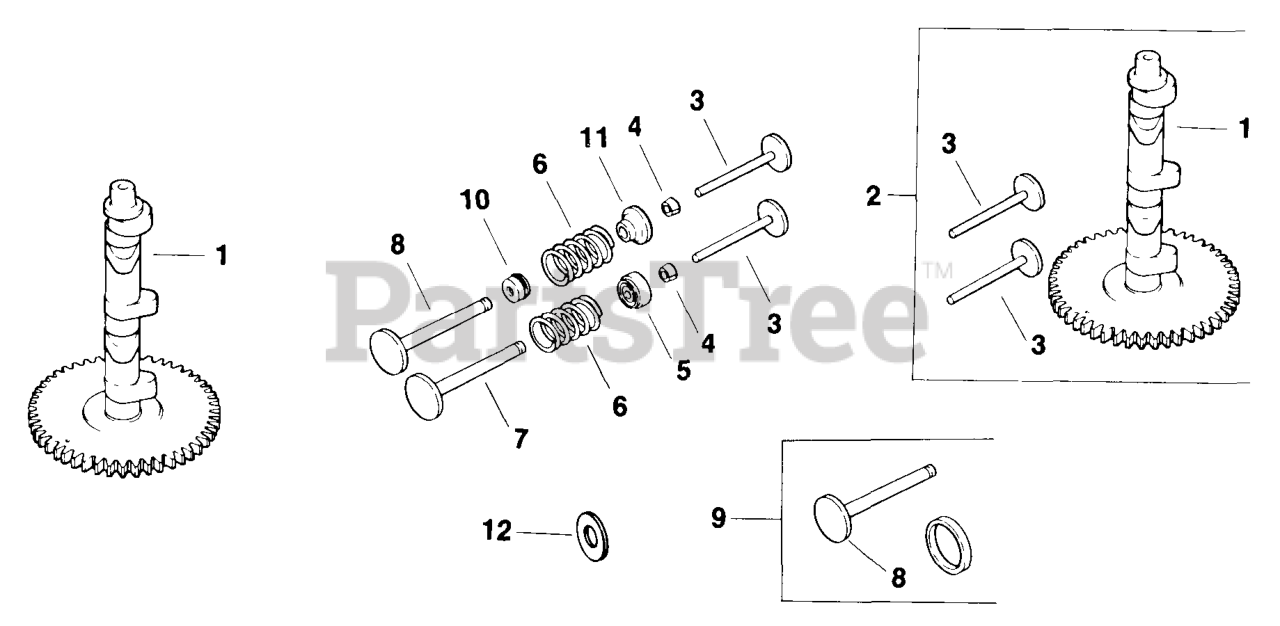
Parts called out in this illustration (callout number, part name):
1	Camshaft
2	Kit, Camshaft
3	Tappet
4	Kit, Retainer
5	Rotator, Exhaust Valve
6	Spring, Valve
7	Valve, Exhaust
8	Valve, Intake
9	Kit, Valve
10	Seal, Intake Valve Stem
11	Retainer, Intake Valve
